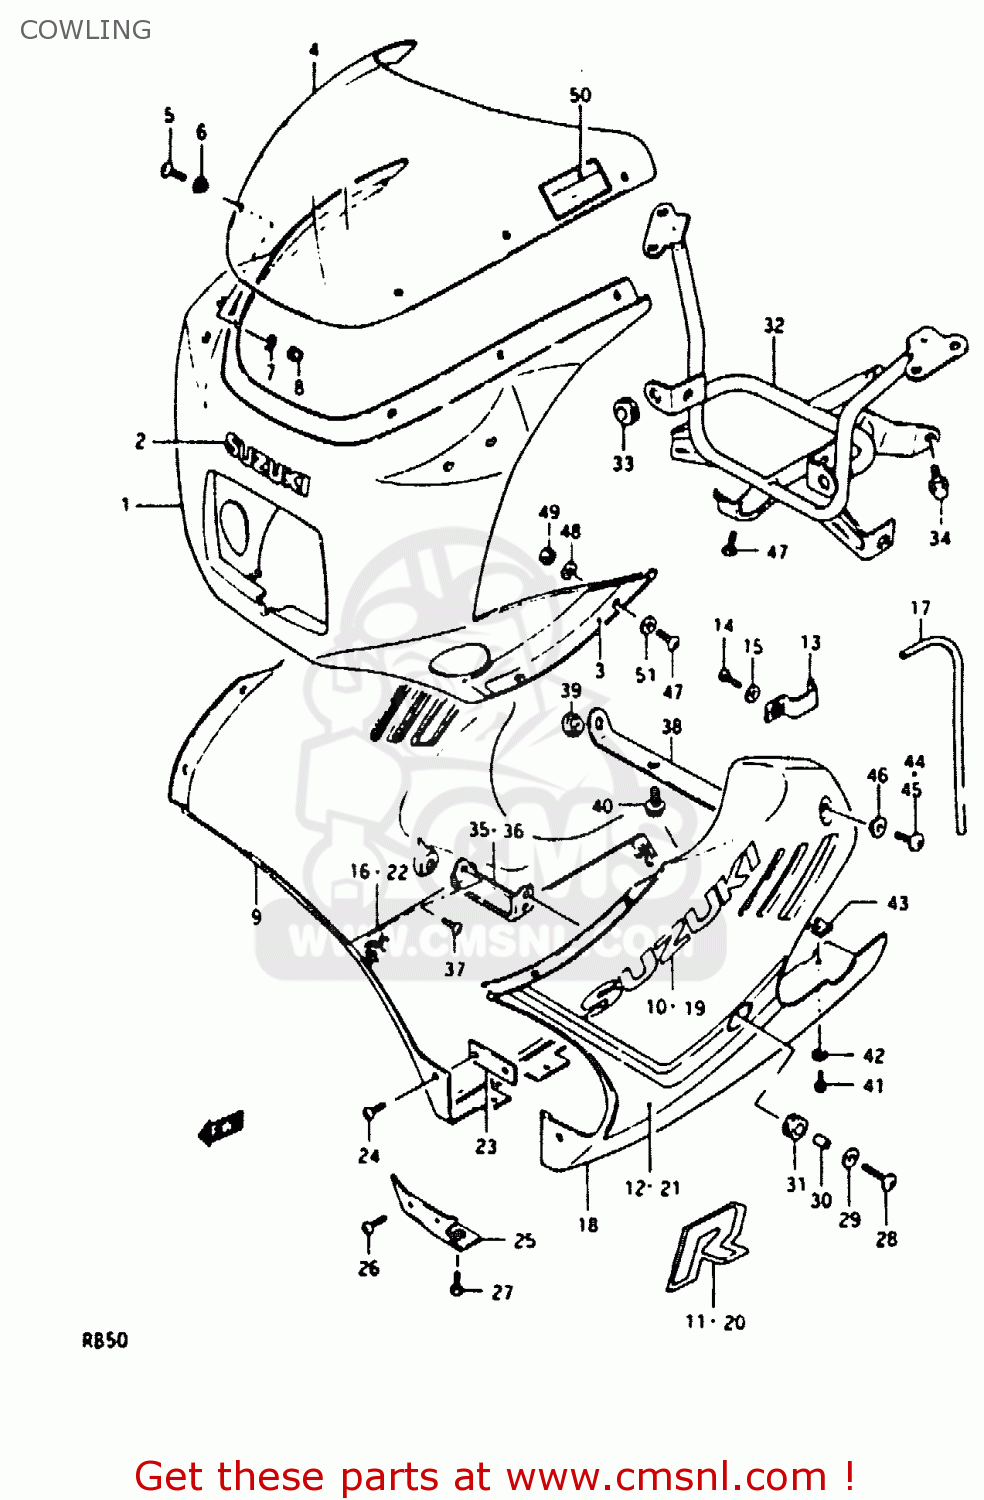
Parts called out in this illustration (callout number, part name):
1	BODY ASSEMBLY,COWLING SUB
2	EMBLEM(WHITE)
3	TAPE SET,COWLING,FRONT
4	WINDOW,COWLING
5	SCREW
6	CUSHION
7	WASHER,5MM
8	NUT 8MM
9	BODY ASSEMBLY,COWLING
10	EMBLEM
11	EMBLEM,COWLING SIDE
12	TAPE SET,COWLING SIDE
13	CLAMP
14	SCREW
15	WASHER
16	SHIELD,UNDER COWL HEAT,R
17	HOSE
18	COVER SET,COWLING,LEFT
19	EMBLEM
20	EMBLEM,COWLING SIDE
21	TAPE SET,COWLING SIDE
23	BRACKET,COWLING LWR
24	SCREW
25	BRACKET,COWLING LWR
26	SCREW
27	SCREW
28	SCREW
29	WASHER(6.5X18X1)
30	SPACER (6.1X9X9)
31	CUSHION
32	BRACE,COWLING
33	CUSHION
34	BOLT
35	BRACE,COWLING LWR,R
36	BRACE,COWLING,LOWER,LEFT
37	SCREW
38	PLATE,COWLING SUPPORT
39	CUSHION
40	BOLT
41	SCREW
42	WASHER(5.2X16X1)
43	NUT
44	SCREW 6X12
45	SCREW(6X16)
46	WASHER
47	SCREW
48	WASHER
49	NUT
51	WASHER
